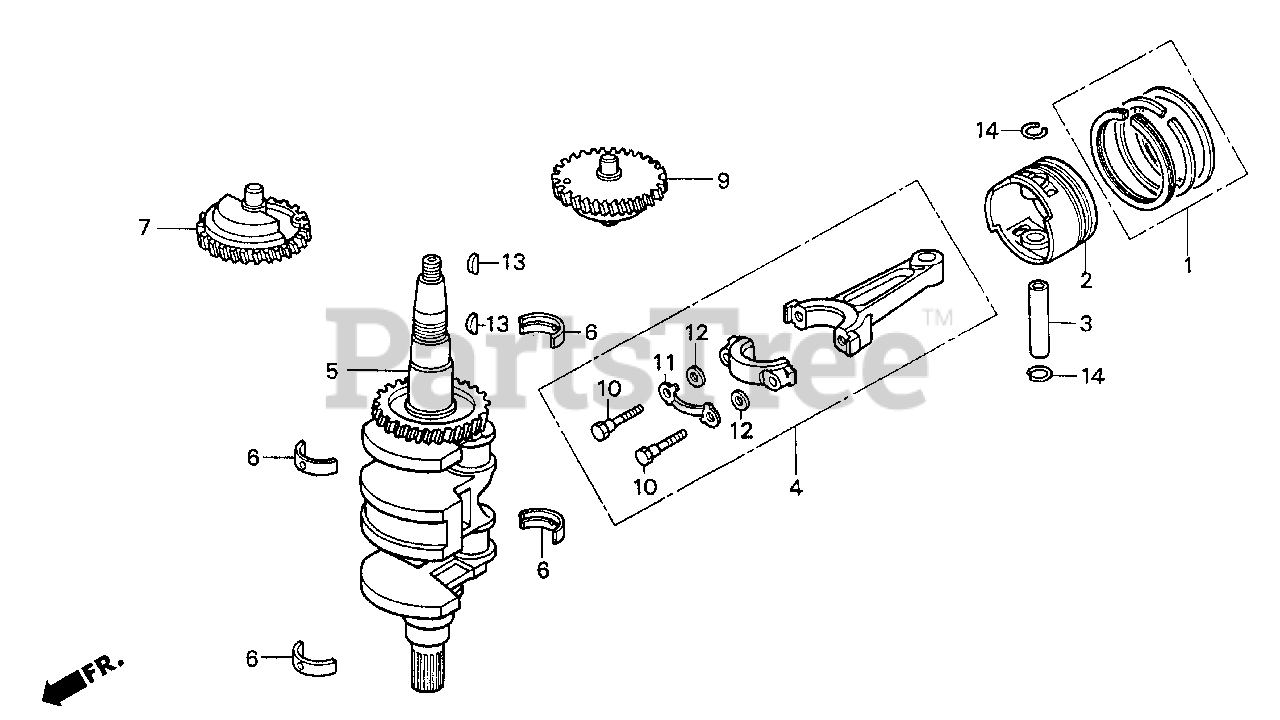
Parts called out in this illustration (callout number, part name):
1	RING SET, PISTON
2	PISTON (NA USE ALT:04101-ZV4-000)
2	PISTON
3	PIN, PISTON
4	ROD ASSY., CONNECTING
5	CRANKSHAFT
6	BEARING, CRANKSHAFT (1) (BLACK)
6	BEARING, CRANKSHAFT (2) (BROWN)
6	BEARING, CRANKSHAFT (3) (GREEN)
6	BEARING, CRANKSHAFT (4) (YELLOW)
6	BEARING, CRANKSHAFT (5) (RED)
7	WEIGHT A, BALANCER
9	WEIGHT B, BALANCER
10	BOLT, CONNECTING ROD
11	WASHER, TONGUED
12	WASHER, PLAIN (7MM)
13	KEY, SPECIAL (16X15)
14	CLIP, PISTON PIN (14MM)
